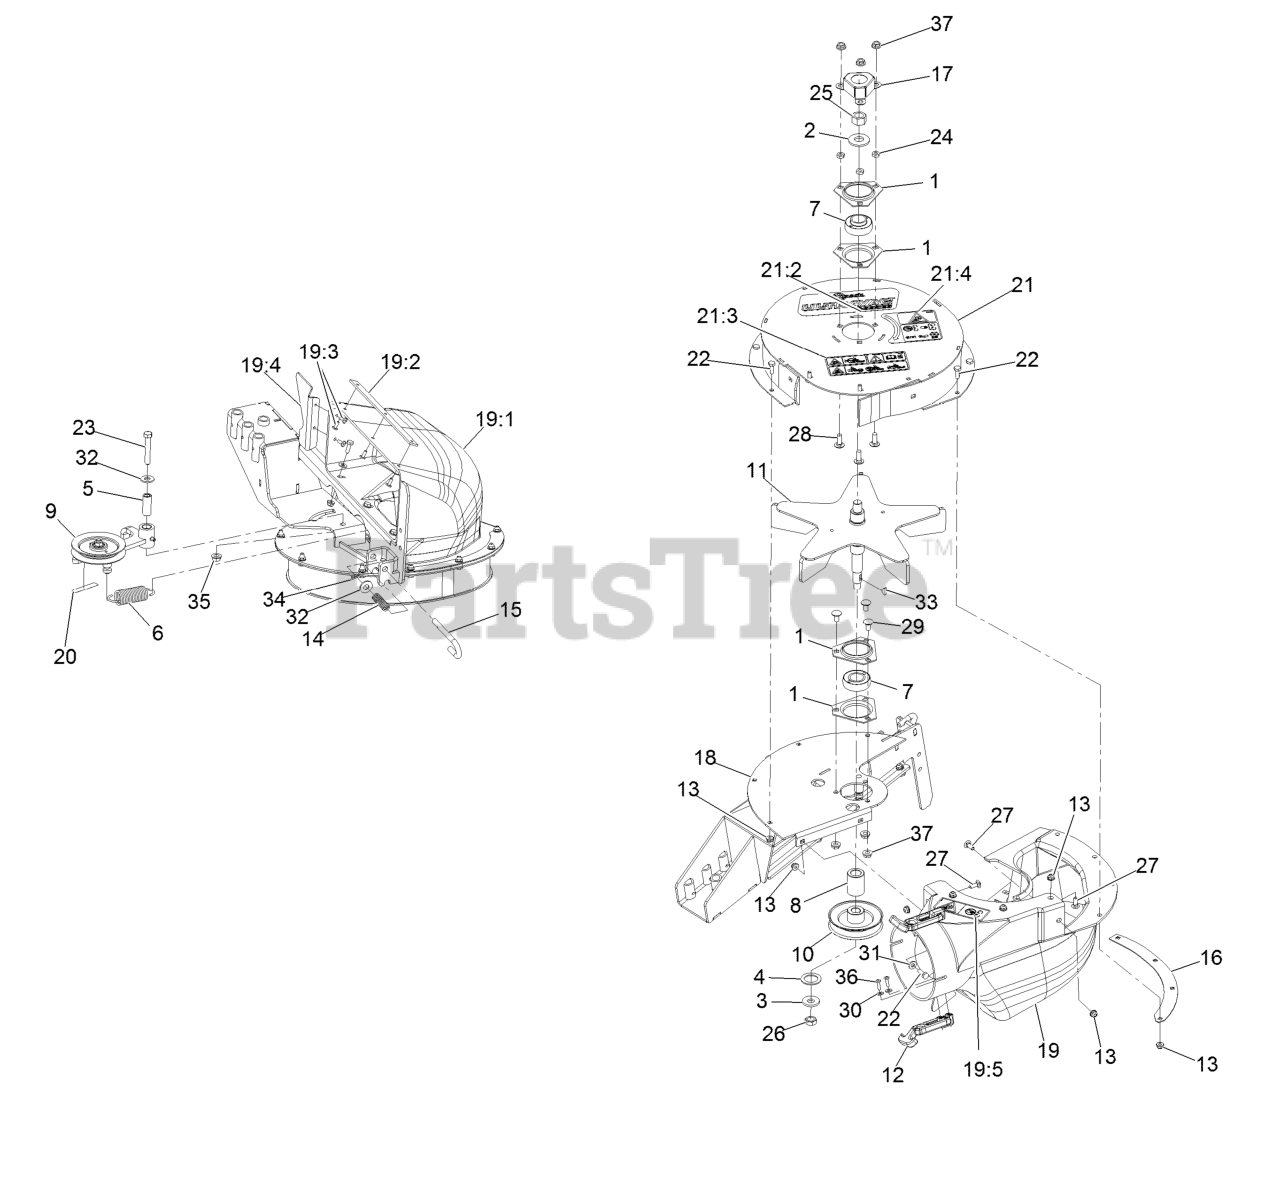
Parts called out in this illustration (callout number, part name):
1	Housing-Flange
2	Washer-Spring Disc 5/8
3	Washer-Spring Disc 1/2
5	Bushing
7	Bearing
9	Asm, Idler
10	Sheave-Blower
11	Impeller
12	Latch-Rubber
13	Nut-Nyloc 1/4-20 Flg
14	Spring-Compression
15	Pin-Latch
16	Plate-Backing
17	Cover-Nut
18	Blower Frame ASM [black]
19	Blower Chute ASM
19:1	Chute-Blower, Small
19:2	Plate-Reinforcing
19:4	Plate-Filler
19:5	Decal-Warning
20	Decal-Warning
21	Upper-Housing W/Decal
21:2	Decal-Ultravac E-Series
21:3	Decal-Warning
21:4	Decal-Warning
22	Screw-HH 1/4-20 X 3/4
23	Screw-HH 3/8-16 X 2 1/4
24	Nut-Jam 5/16-18
25	Nut-Hex 5/8-18
26	Nut-Jam 1/2-20
27	Bolt-Carriage 1/4-20 X 3/4
28	Bolt-Carriage 5/16-18 X 7/8
29	Bolt-Carriage 5/16-18 X 5/8
30	Washer-#10 Std
31	Washer-1/4 SAE
32	Washer-3/8 Std
33	Key-Woodruff 3/16 X 5/8
34	Pin-Cotter
35	Nut-Whizlock 3/8-16
36	Screw-PPH #10-24 X 5/8
37	Nut-Whizlock 5/16-18
